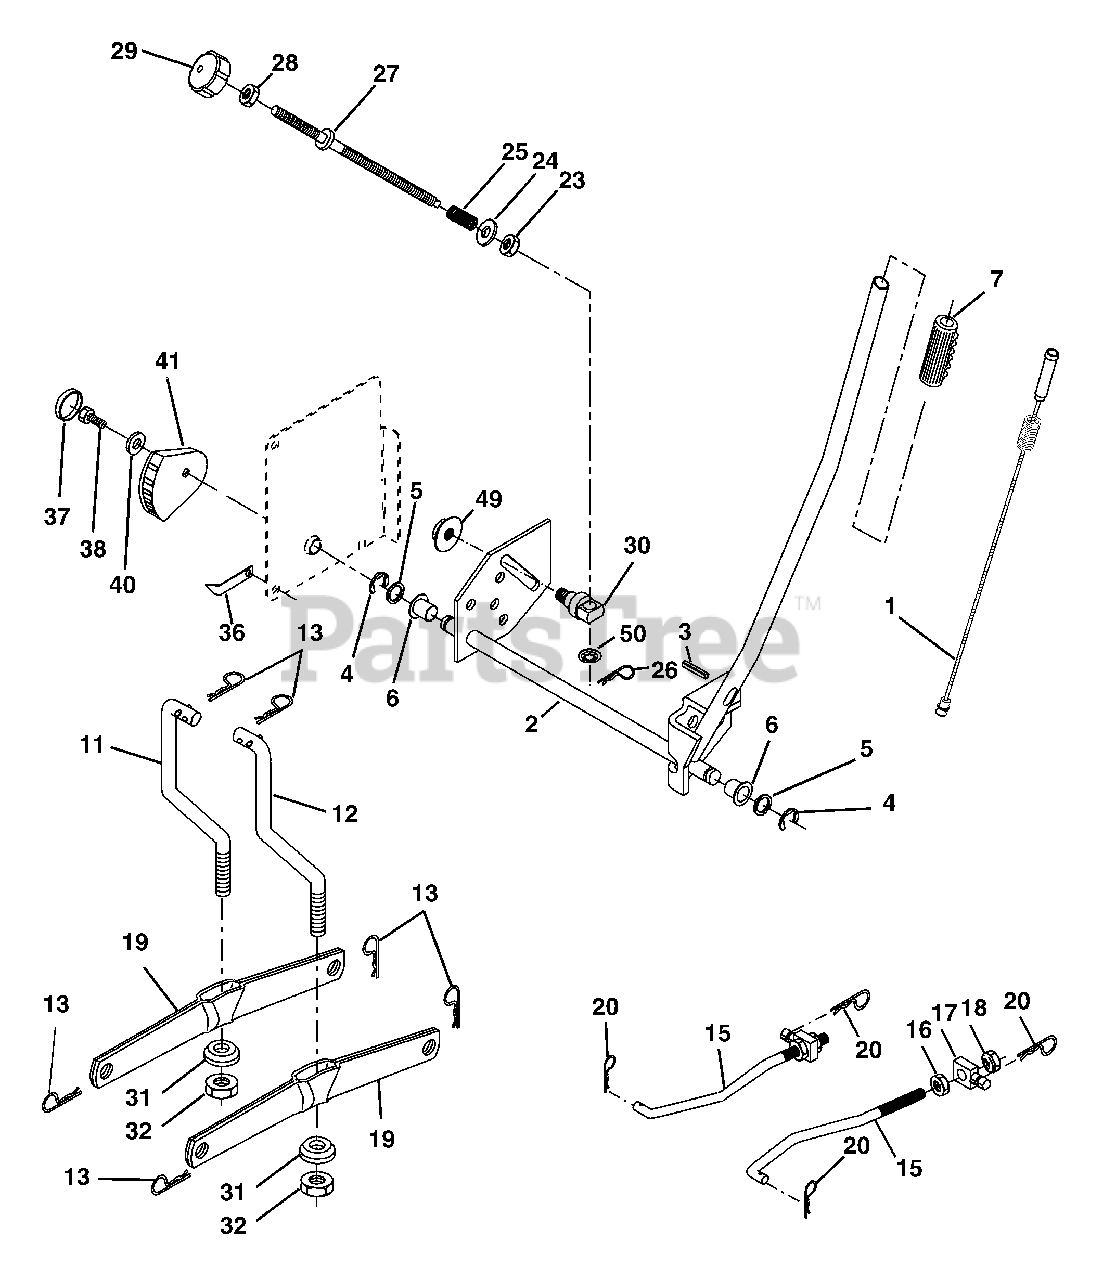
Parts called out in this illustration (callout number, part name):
1	Plunger Asm.
2	Shaft Asm Lift
3	Pin Groove
4	E Ring #5133-62
5	Washer 21/32 x 1 x 21 Ga.
6	Bearing Nylon
7	Grip Handle
11	Link Lift Lh
12	Link Lift Rh
13	Retainer Spring
15	Link Front
16	Nut Jam Hex 1/2-13 Unc
17	Trunnion Blk Zinc
18	Nut Lock w/Wsh 1/2-13 Unc
19	Arm Suspension Rear
20	Retainer Spring
23	Nut Special
24	Washer 13/32 x 5/8 x 16 Ga.
25	Spring
26	Retainer Clip
27	Rod Adj. Lift
28	Nut Hex Jam 3/8-16 Unc
29	Knob
30	Trunnion Infin. Height
31	Bearing Pvt Lift
32	Nut Crownlock 3/8-24
36	Pointer Height Indicator
37	Plug Hole
38	Screw 5/16-18 x 1
40	Washer 11/32 x 1-1/2 10 Ga.
41	Indicator Height
49	Nut Hex Flange Lock
50	Nut Push
